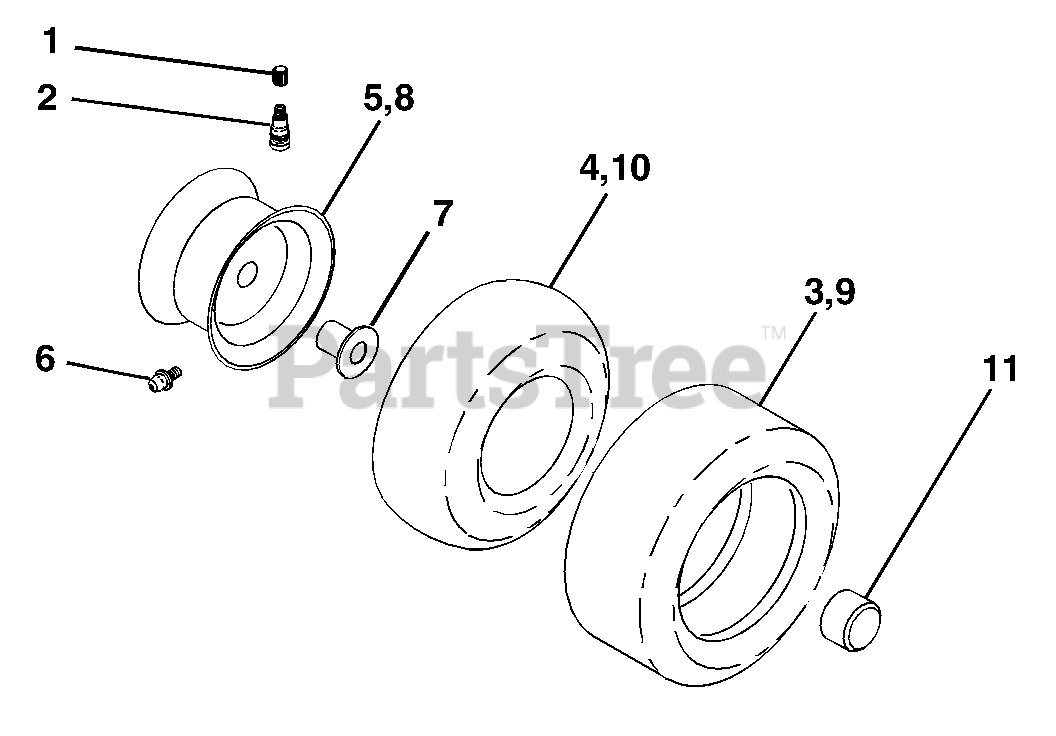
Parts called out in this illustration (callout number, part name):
1	Cap Valve Tire
2	Stem Valve
3	Tire F T 15 x 6 0 - 6 Service
4	Tube Front (Service Item Only)
5	Rim Asm 6"front Service
6	Fitting Grease (Front Wheel Only)
7	Bearing Flange (Front Wheel Only)
8	Rim Asm 8"rear Service
9	Tire R T 20 x 10 -8 C Service
10	Tube Rear (Service Item Only)
11	Cap Axle 1 50 x 1 00
